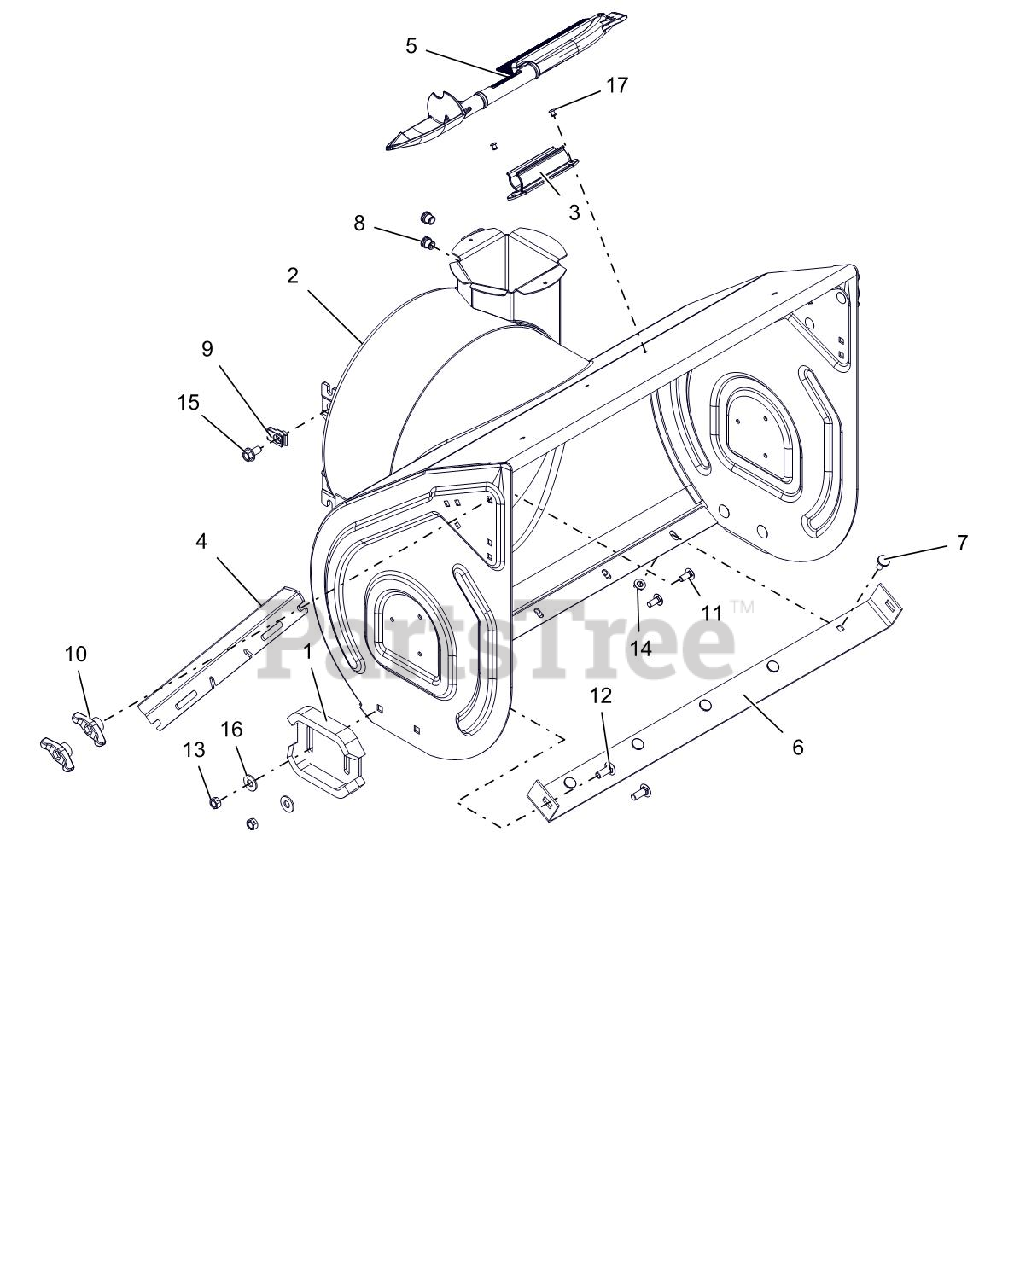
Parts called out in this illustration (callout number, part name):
1	RUNNER, SKID SHOE
2	BLOWER HOUSING W/DECAL 28"
3	MOUNT, SNOW CLEAN OUT
4	CUTTER, DRIFT
5	DEVICE, SNOW CLEAN OUT W/BRUSH
6	BLADE, SCRAPER-28"
7	BOLT, MODIFIED HEAD CARRIAGE
8	NUT, THREADED INSERT .38-16
9	NUT-RTNR .375-16X.37
10	KNOB,WING .31-18 UNC NYL/TALC
11	@BLT-RHDSSQNK .31-18X.75 G5YZ
12	@BLT-RDHDSHSQNK.38-16X1.0 G5YZ
13	@NUT-LK-CTR .38-16 YWZC
14	@NUT-LK-TOP-FLG .31-18 YWZC
15	BLT-SERHFWH .38-16X.75 YWZC
16	@WSHR-FL-STL.438X1.00X.083 YWZ
17	RVT-POP .187 YZ
